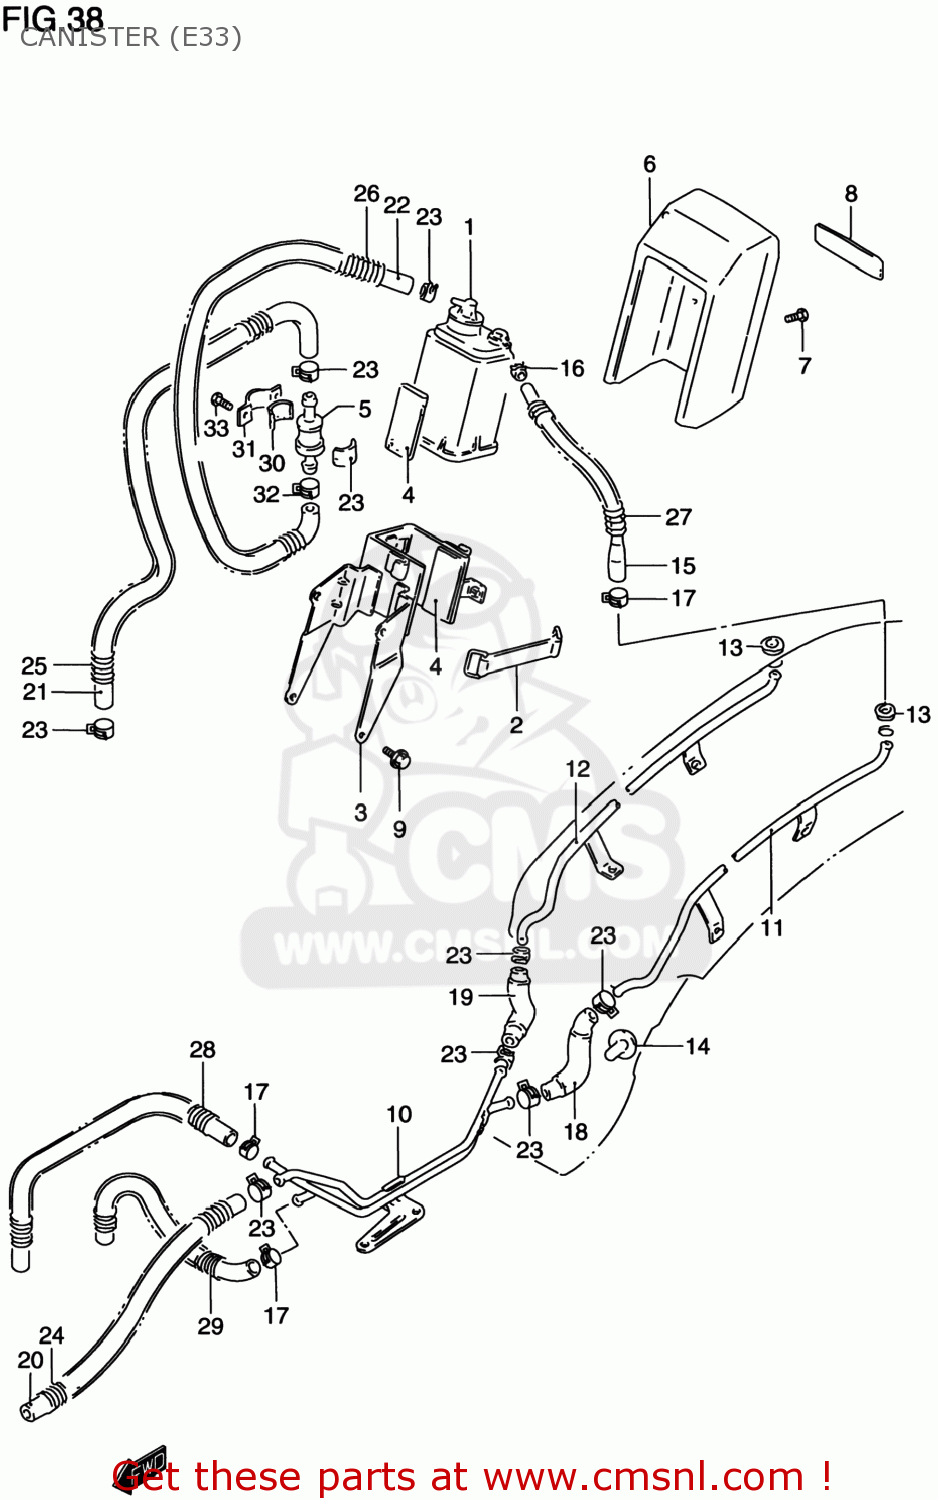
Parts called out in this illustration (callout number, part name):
1	CANISTER ASSY,CHARCOAL
2	BAND
3	PLATE,CANISTER FITING
4	CUSHION
5	CUSHION
6	COVER,CANISTER
7	SCREW
8	EMBLEM,TOOL HOLDER RR
9	BOLT
10	PIPE,CSTR JOINT FR
11	(CA) PIPE,CANISTER JOINT REAR
12	(CA) PIPE,CANISTER JOINT REAR
13	GROMMET
14	GROMMET
15	HOSE,PURGE NO.1
16	CLIP
17	CLIP
18	(CA) HOSE NO.6
19	(CA) HOSE NO.2
20	HOSE(5.4X11.4X600)
21	HOSE
22	HOSE
23	CLIP
24	SPRING
25	(CA) SPRING
26	SPRING
27	SPRING
28	SPRING
29	SPRING
30	VALVE,FUEL TANK BREATHER
31	PLATE,FUEL TANK BREATHER NO.2
32	CUSHION
33	SCREW
